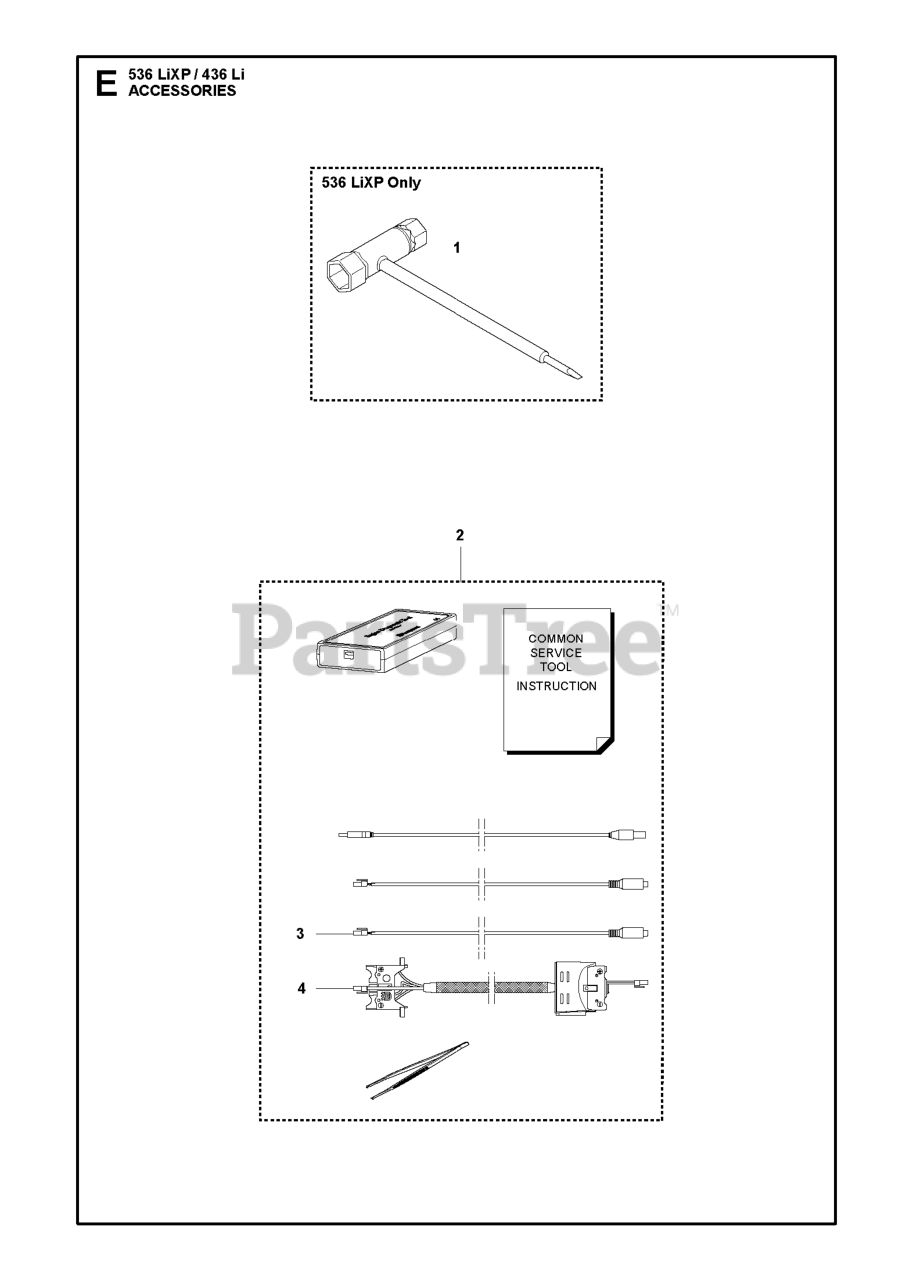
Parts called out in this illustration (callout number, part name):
1	COMBI TOOL
2	DIAGNOSTIC TOOL KIT
3	CABLE ASSY
4	WIRING ASSY
